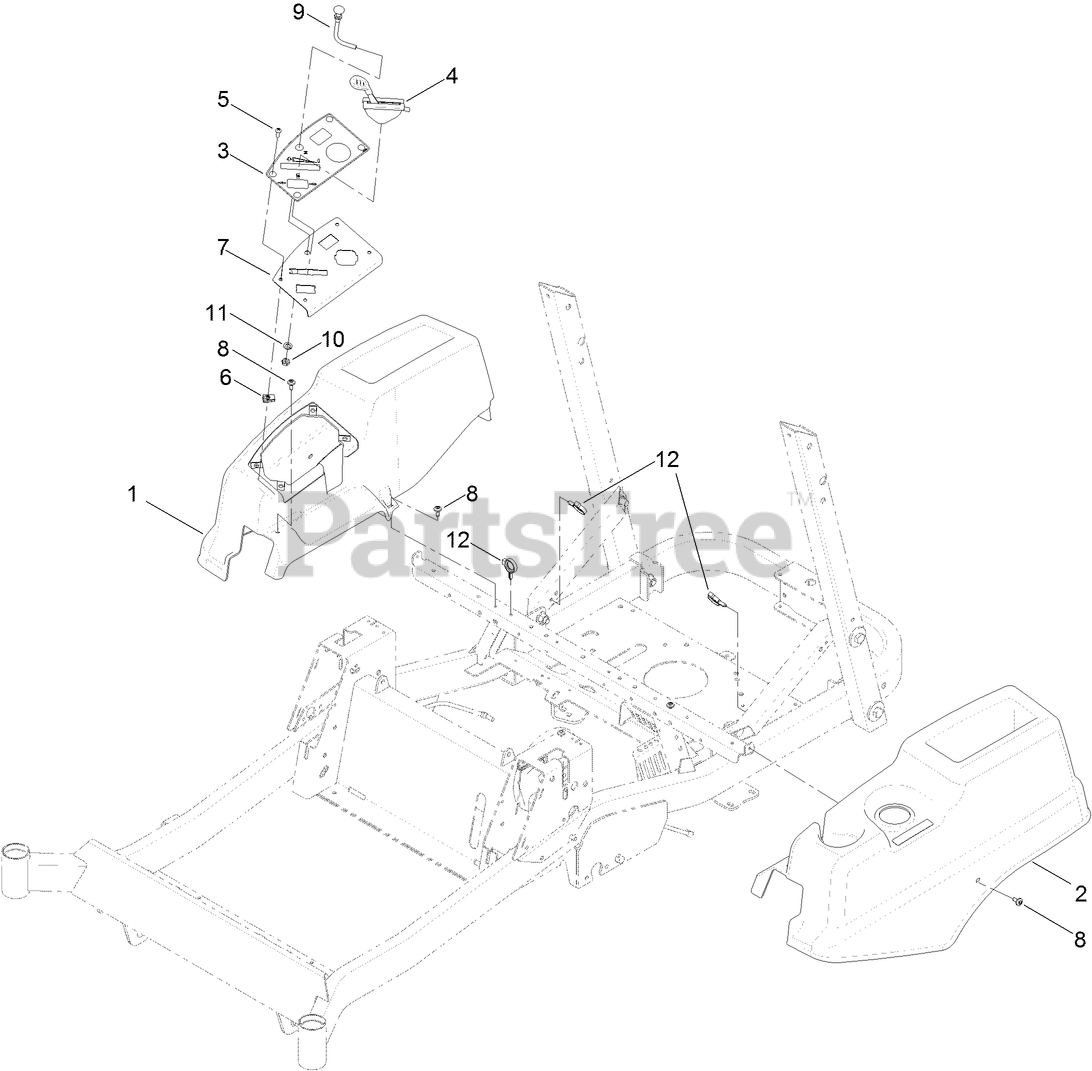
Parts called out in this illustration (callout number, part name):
1	POD-RH
2	POD-LH
3	DECAL-PANEL, CONTROL
4	CABLE-THROTTLE
5	SCREW-PRH
7	PANEL-CONTROL
8	SCREW-SHOULDER
9	CABLE-CHOKE
10	WASHER-LOCK
11	NUT-HJ
12	CLAMP-HOSE
